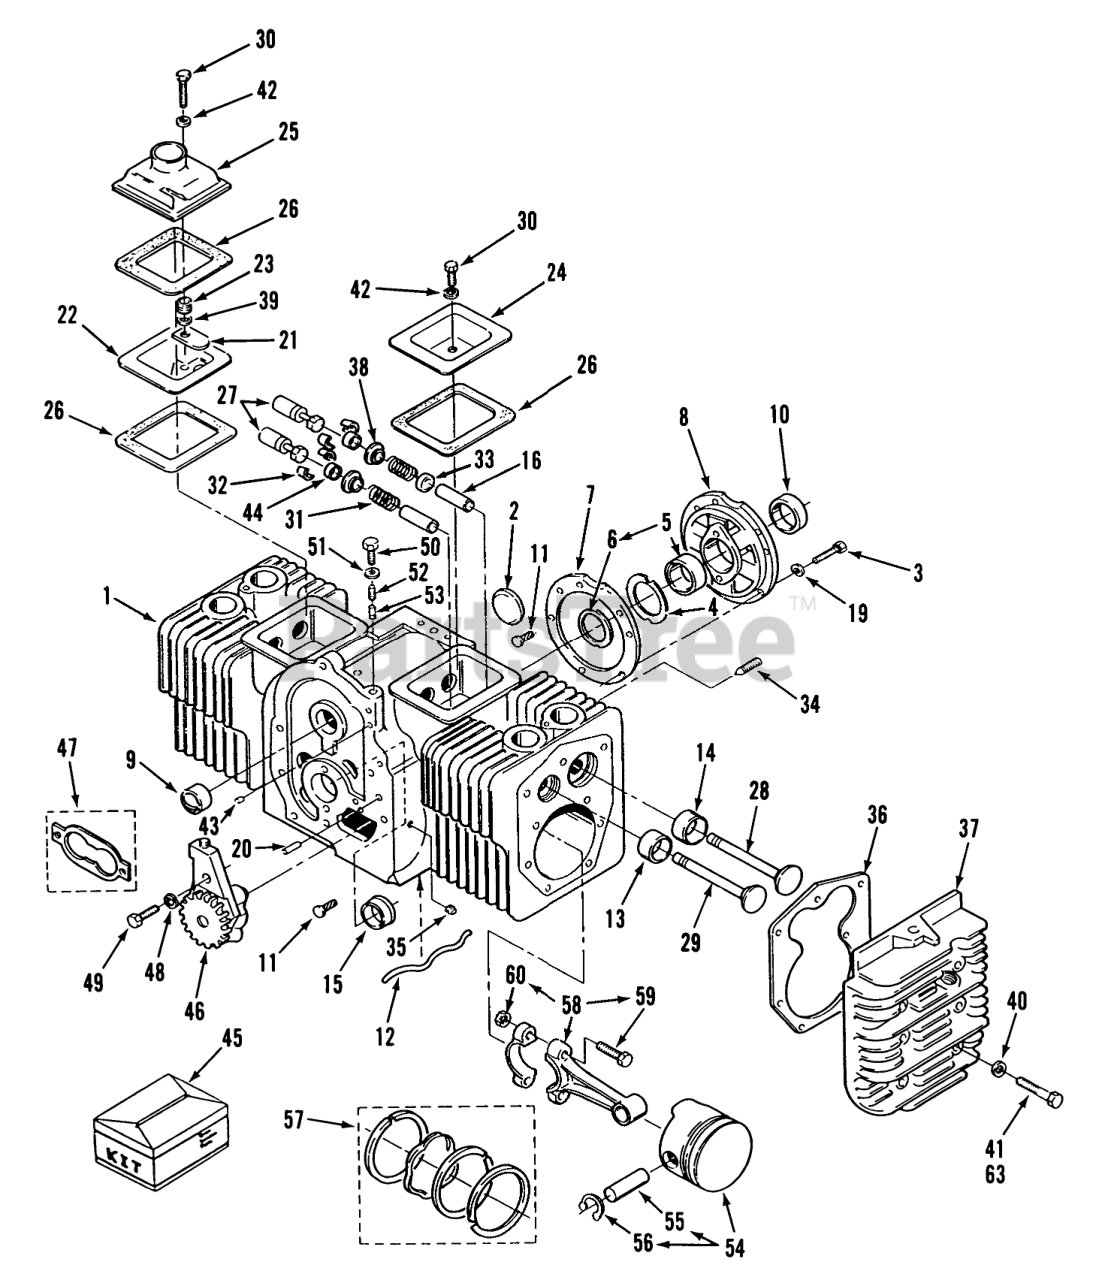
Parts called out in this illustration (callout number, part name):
1	Shortblock
1	Short Block 18 & 20 HP
2	Plug
3	Bolt 3/8-16x 1-1/4
4	Shim 0.005"
5	Rear Crankshaft Bearing-STD
5	Rear Crankshaft Brg-.002 under
5	Rear Crankshaft Brg-.010 under
5	Rear Crankshaft Brg-.020 under
5	Rear Crankshaft Brg-.030 under
6	ThrustWasher
7	Gasket
8	Bearing Plate
9	Camshaft Brg
10	Oil Seal
11	Screw
12	Oil Tube
13	Standard
13	.002" Oversize
13	.005" Oversize
13	.010" Oversize
13	CYLINDER BLOCK ASS'Y
14	Standard
14	002" Oversize
14	005" Oversize
14	010" Oversize
14	025" Oversize
15	Standard
15	.002" Undersize
15	.010" Undersize
15	.020" Undersize
15	.030" Under
16	Exhaust Valve Guide
16	Intake Valve Guide
19	Lockwasher 3/8
20	Pin
21	Valve Reed
22	Baffle
23	Spring
24	RH Valve Cover
25	L.H. VALVE COVER
26	Gasket
27	Tappet
27	.002" Oversize
27	.005" Oversize
28	Intake Valve
29	Exhaust Valve
30	HHCS 1/4-20 X 1 3/4
31	Spring
32	VALVE SPRING LOCK
33	Seal
34	Screw
35	Plug
36	Gasket
37	Right Side
37	Side-Left
38	Washer
39	Washer
40	Washer
41	Bolt
42	Washer
43	Plug
44	Cap-Valve
45	Engine Gasket Kit
45	Valve Grind/Carbon Removal
46	Oil Pump
47	Oil Pump Gasket Kit
48	Washer-Lock
49	Bolt
50	Bolt
51	Washer
52	Spring
53	Piunger
54	Piston Pin & Retaining Rings-STD
54	Piston Pin & Retaining Rings-.005"
54	Left Side
54	Piston Pin & Retaining Rings-.020"
54	Piston Pin & Retaining Rings-.030"
54	Piston Pin & Retaining Rings-.040"
55	Pin-Piston
56	Retaining Ring
57	Standard
57	.005" Oversize
57	.010" Oversize
57	.020" Oversize
57	.030" Oversize
57	Piston Ring Set.040" Oversize
58	CONNECTING ROD W/NUT
58	Rod w/Bolts & Nuts-STD
58	Rod w/Bolts & Nuts-.010"
58	Rod w/Bolts & Nuts-.020"
58	Bolt-Rod
59	Rod Bolt
60	Nut
63	Special Bolt 2.375" Long
